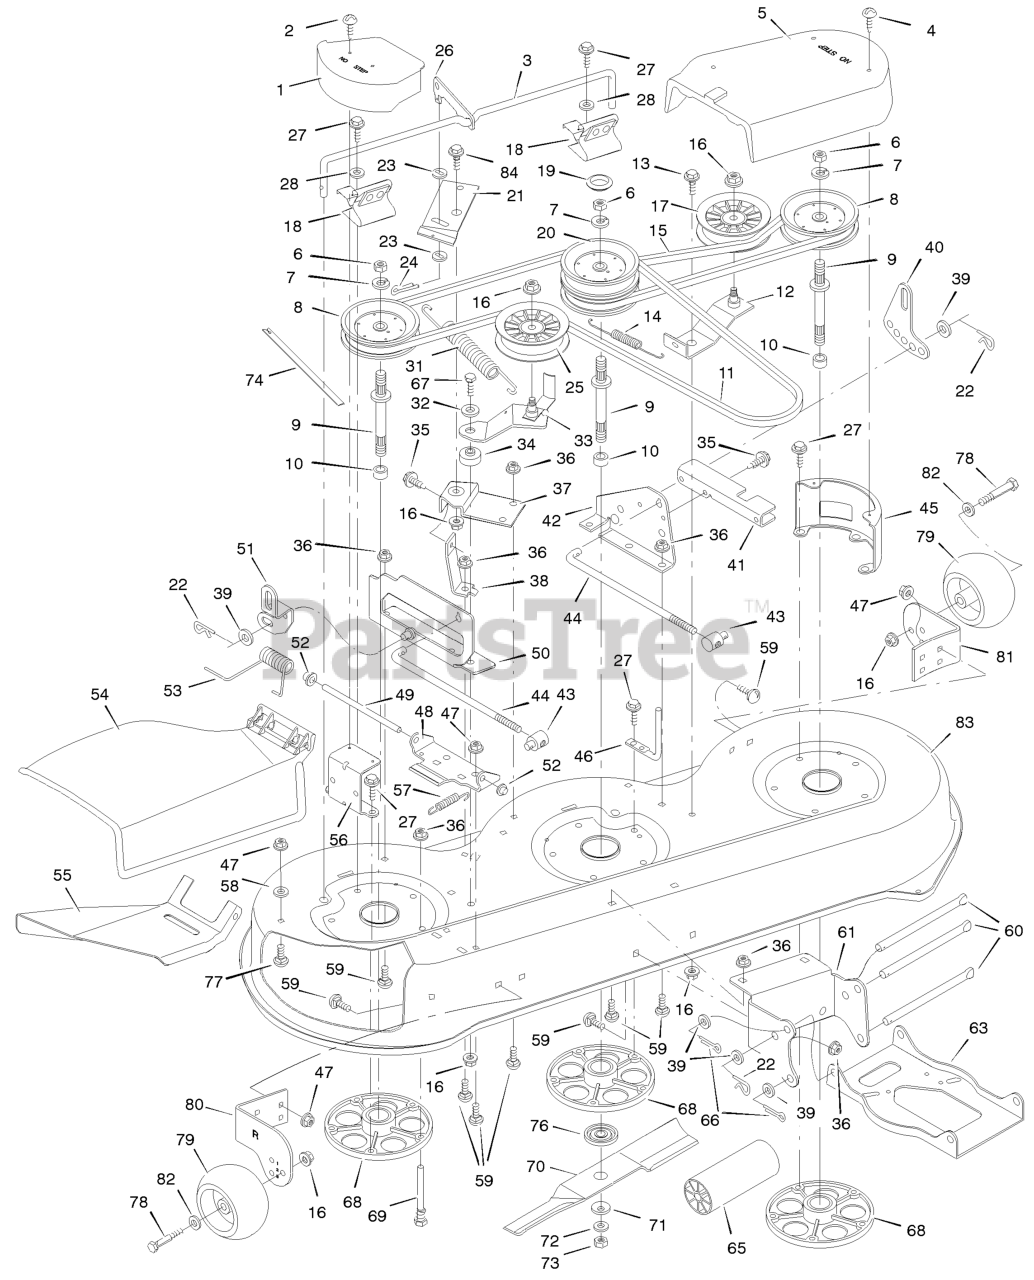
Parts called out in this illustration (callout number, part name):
1	Cover, Pulley
3	Rod, Brake
5	Cover, Left Pulley
6	Nut, Hex
7	Lockwasher
9	Jackshaft
10	Spacer, Bearing
11	Belt, Primary Mower Drive
12	Bracket, Idler
13	Bolt, Shoulder
14	Spring, Extension
15	Belt, Secondary Mower Drive
16	Locknut
17	Pulley, Idler
18	Spring Assembly, Brake
20	Pulley, Stack
21	Bracket, Pivot
22	Pin, Hair
24	Pin, Cotter
25	Pulley, Idler
26	Link, Brake
27	Screw
31	Spring, Extension
33	Bracket, Idler
34	Bushing
36	Nut, Hex
37	Support, Pivot
38	Strut, Pivot
40	Plate, Adjuster
41	Channel, Left Cover
42	Bracket Assembly, Lifter
43	NUT, Adjusting, 1/2-13
44	Rod, Adjuster
45	Bracket, Left Cover
46	Guide, Belt
47	Locknut
48	Bracket, Hinge
49	Rod, Deflector
50	Bracket Assembly, Lifter
51	Link, Suspension
52	Push- On Cap
53	Spring, Torsion
54	Deflector
55	Deflector, Inside
56	Bracket, Cover
57	Spring, Extension
59	Bolt, Carriage
60	Rod, Hanger
61	Bracket, Front Hanger
63	Hanger, Front
66	Pin, Cotter
67	Bolt, Hex
68	Housing, Mandrel
69	Guide, Belt
70	Blade (3 required)
71	Washer, Belleville
73	Nut, Hex
74	Indicator, Plastic
76	Adapter, Blade
77	Bolt, Carriage
78	BOLT, Gauge Wheel
79	Wheel, Gauge
80	Bracket, Right Gauge Wheel
81	Bracket, Left Gauge Wheel
82	Washer
83	Housing, Mower
84	Bolt, Shoulder
